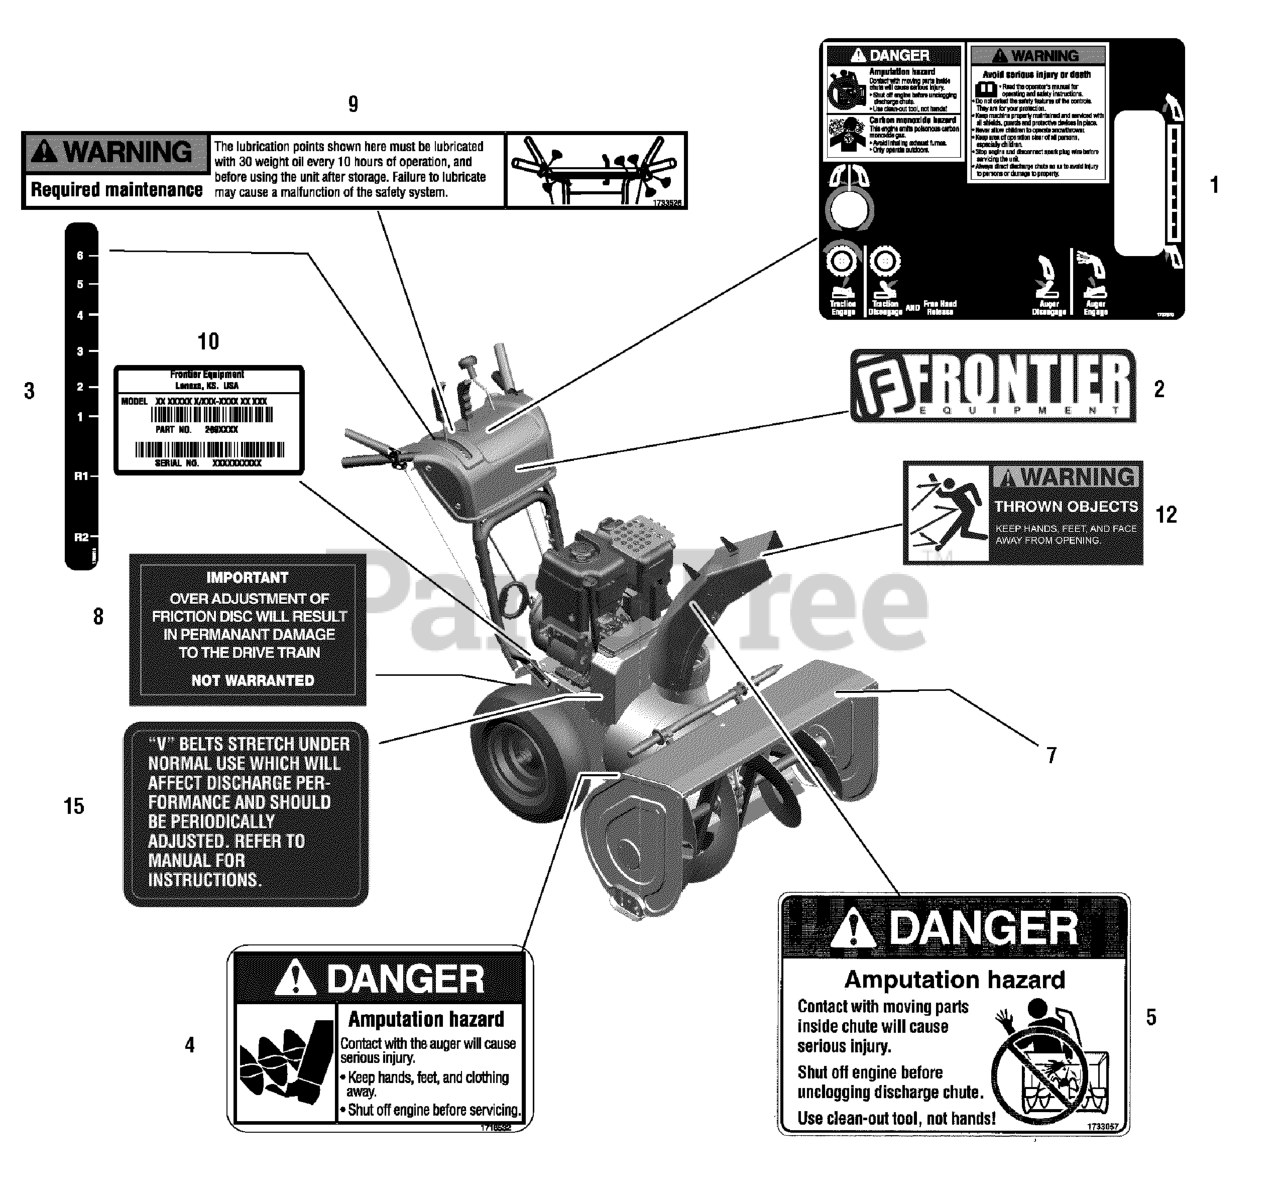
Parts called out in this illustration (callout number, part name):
1	DECAL, Dashboard
2	PLATE, Frontier
3	DECAL, Shift
4	DECAL, Danger Avoid Injury from Auger
5	DECAL, Danger Amputation Hazard
6	DECAL, OPEI Certified ANSI *
7	DECAL, ST8526
7	DECAL, ST9528
8	DECAL, Over Adjustment of Friction Disc
9	DECAL, Lubrication
10	STICKER, Serial with Bar Code
12	DECAL, Thrown Objects
15	DECAL, V-Belt Adjustment
